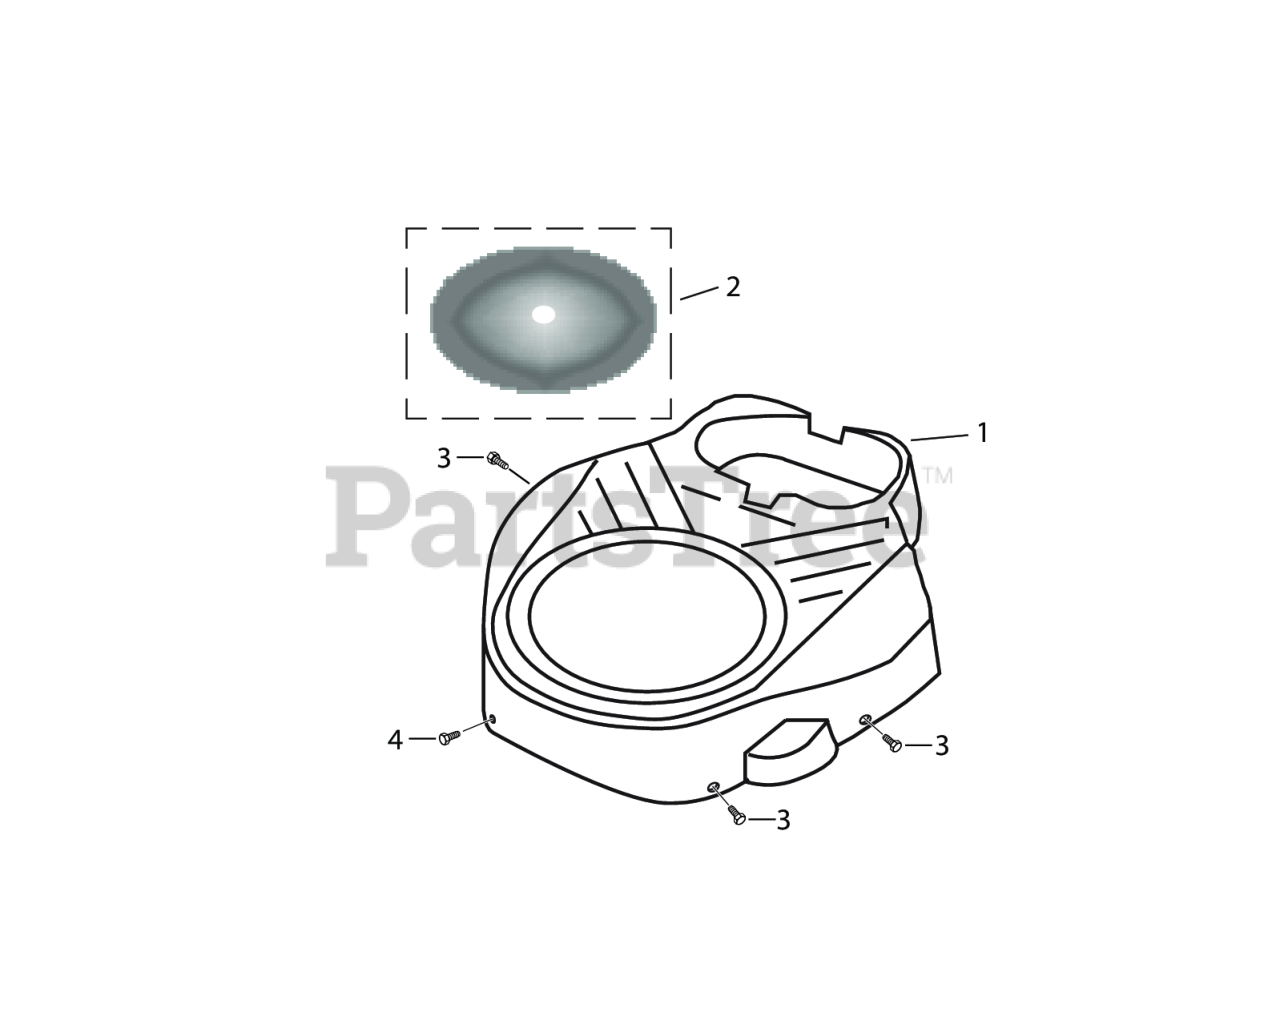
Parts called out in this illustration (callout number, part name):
1	Shroud
2	Cover, Flywheel
3	BEARING, CUTTER SPINDLE UPPER
4	BEARING, CUTTER SPINDLE LOWER
